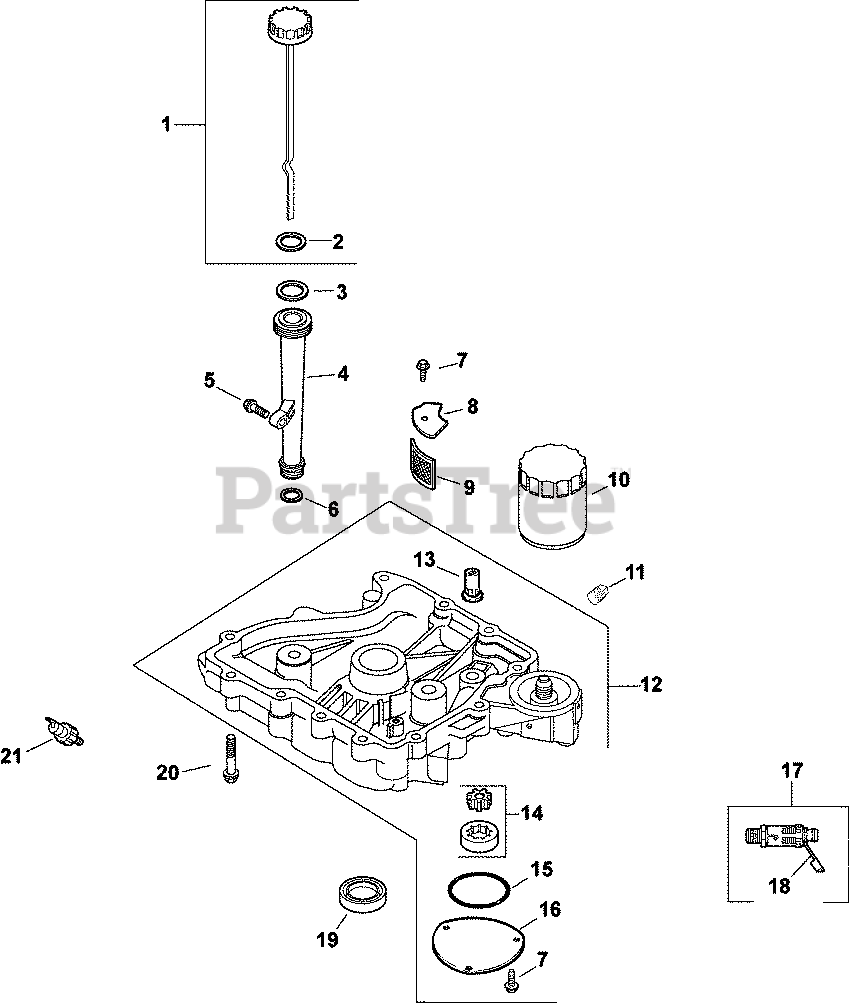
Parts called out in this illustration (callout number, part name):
1	DIPSTICK/CAP ASSY (BLACK)
2	O-RING, DIPSTICK
3	O-RING, UPPER OIL FILL TUBE
4	TUBE, OIL FILL USE 25 123 07-S
5	SCREW,FLG THD FRM M6X1.0X25-(#25086395S)
6	O-RING, LOWER OIL FILL TUBE
7	SCREW,FLG THD FRM M5X0.8X16-(#25086398S)
9	SCREEN, OIL-USE 24 162 26-S
10	OIL FILTER
11	PLUG, SQ HD PIPE 3/8"
12	PAN, OIL
13	VALVE, OIL PRESSURE RELIEF
14	PUMP ASSEMBLY, OIL - DISCONTINUED
15	O-RING (2.5" DIA)
16	COVER, OIL PUMP
17	KIT, OIL DRAIN VALVE
18	CAP, OIL DRAIN VALVE
19	SEAL, OIL
20	SCREW, FLG M8X1.25X45
21	SWITCH, PRESSURE
